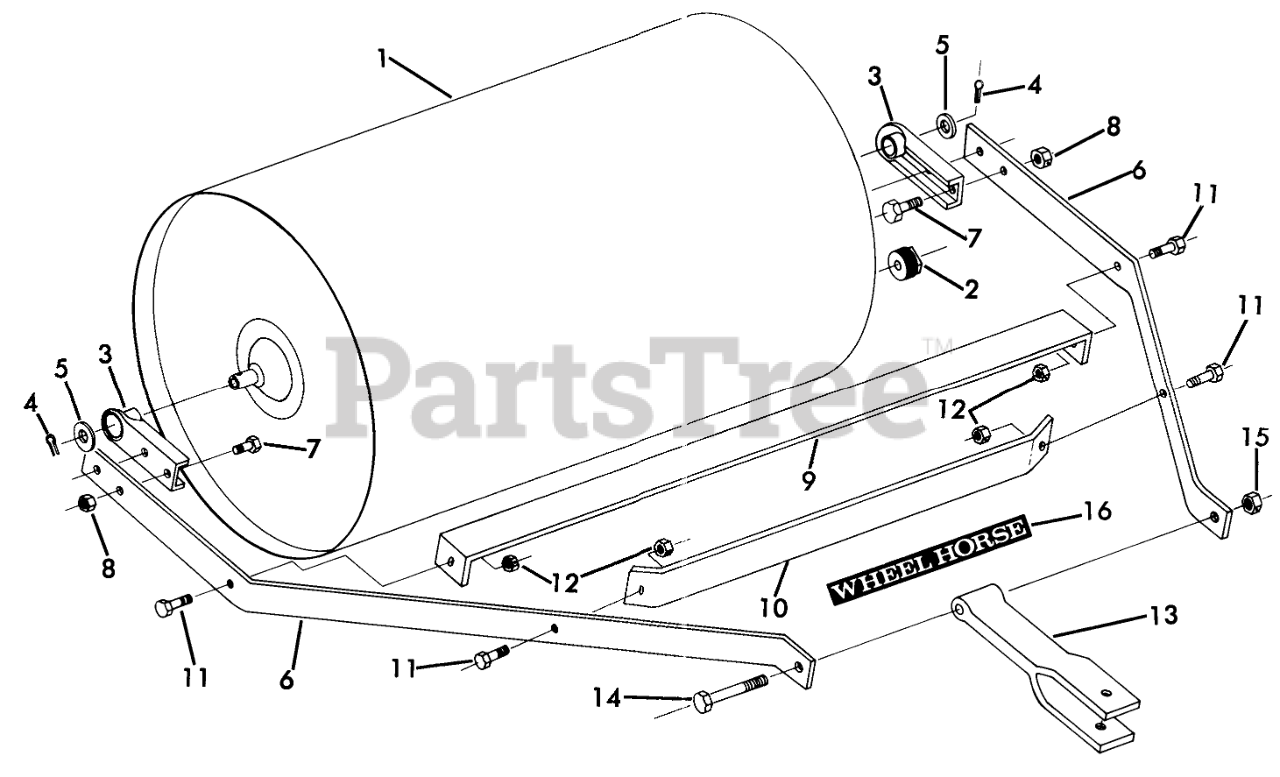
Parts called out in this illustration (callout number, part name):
1	Drum Assembly
2	Pipe Plug
3	Hub (w/Bushing)
4	Pin-Cotter
5	WASHER
6	Frame Side Bar
7	Bolt
8	Nut
9	Scraper Bar
10	Frame Support
11	BOLT
12	NUT
13	HITCH ASSEMBLY
14	Bolt 1/2-13 x 3 1/2
15	Nut
16	DECAL-WHEEL HORSE
